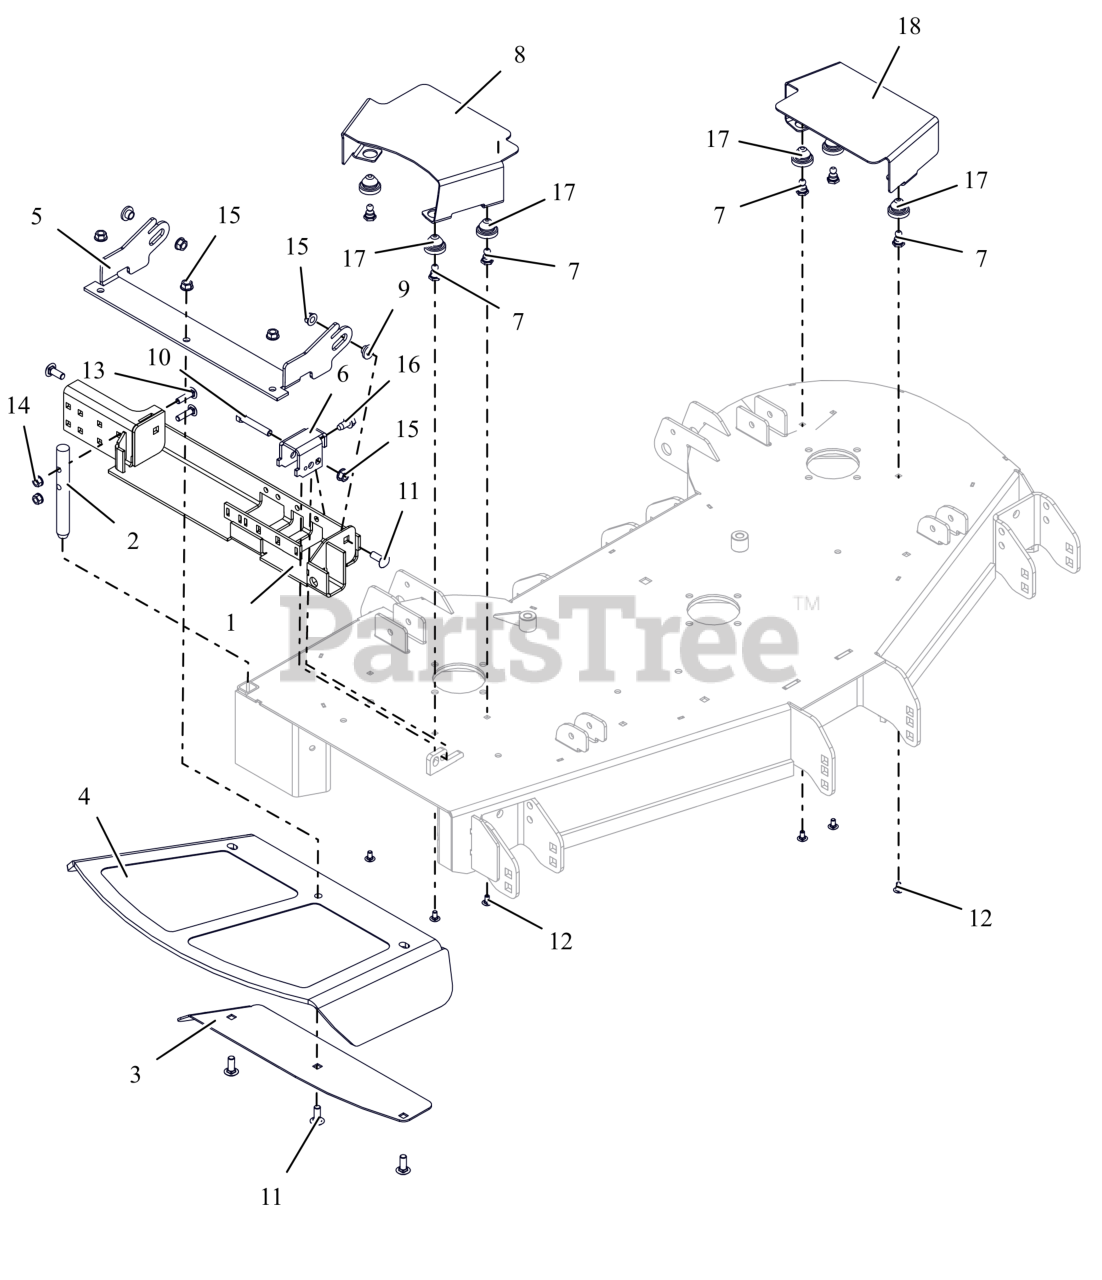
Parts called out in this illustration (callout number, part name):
1	WLDMT, GRASS CATCHER
2	PIN, DISCHARGE CHUTE X-DRILLED
3	48-60 DISCH CHUTE CLMP PLT-BLK
4	CHUTE,48-60" FRMD RUBBER DISCH
5	BRKT, 48-60" CHUTE MTG
6	BRKT, DISCH. CHUTE MTG
7	STUD, BALL FEMALE .250-20 THREAD
8	GUARD, RH DECK BELT (RED)
9	BSHG-FLG .385X.500X.875X.406
10	BLT,HEX .38-16X2.25 G5 ZCC
11	BLT,RHSSN .38-16X1.00 G5 ZCC
12	BLT, RHSSN.25-20X.500 G5 ZCC
13	BTL,RHSSN .313-18 X 1.25 G5 ZCC
14	NUT,LK-CTR-FLG .31-18 GF ZCC
15	NUT-LK-CTR-FLG .375-16 GF ZCC
16	SCR,TAP .375-16X.75 HWH TR ZCC
17	COUPLING, RUBBER PUSH-IN
18	GUARD, LH DECK BELT (RED)
